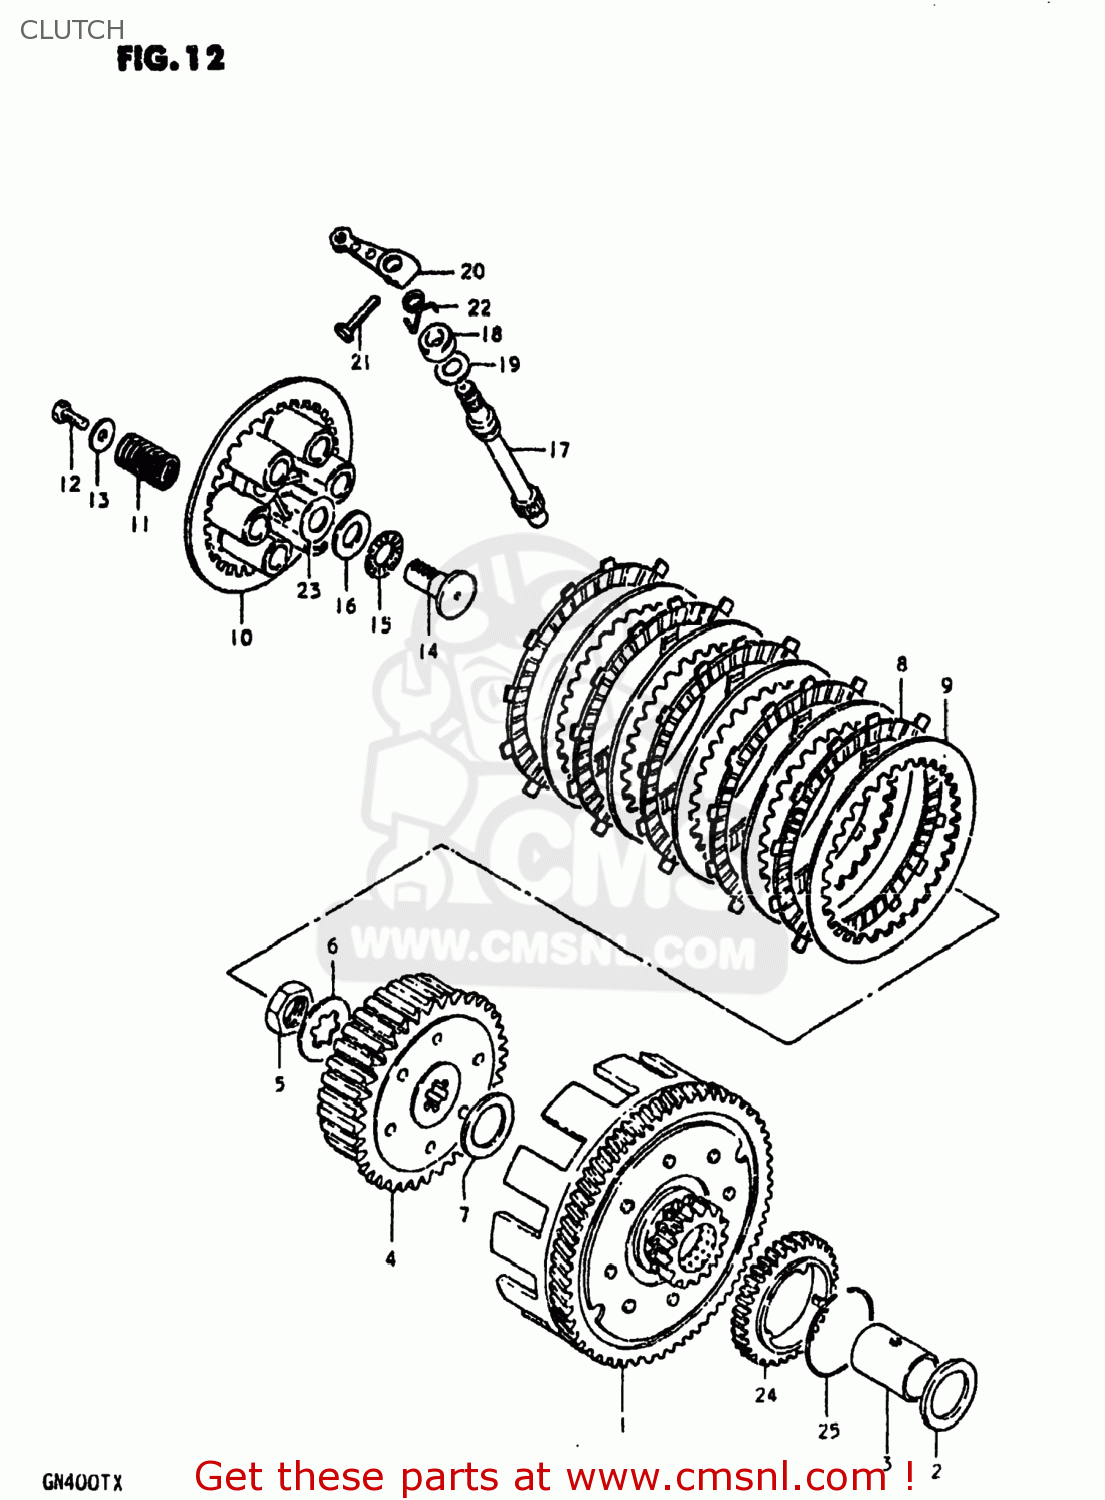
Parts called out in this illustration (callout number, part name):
1	GEAR ASSEMBLY,PRIMARY DRIVE
2	WASHER
3	SPACER
4	HUB,CLUTCH SLEEVE
5	NUT (20MM)
6	WASHER,LOCK
7	WASHER(20X38X2)
8	PLATE,CLUTCH DRIVE (MCA)
9	PLATE,CLUTCH DRIVEN (NAS)
10	DISC,CLUTCH PRESSURE
11	SPRING
12	BOLT, UPPER
13	WASHER
14	RACK,CLUTCH RELEASE
15	BEARING(15X28X2)
16	WASHER
17	PINION,CLUTCH RELEASE
18	OIL SEAL
19	WASHER (14.2X22X1)
20	ARM,CLUTCH RELEASE
21	BOLT,REAR
22	SPRING
23	WASHER
24	GEAR,OIL PUMP DRIVE
25	CIRCLIP
